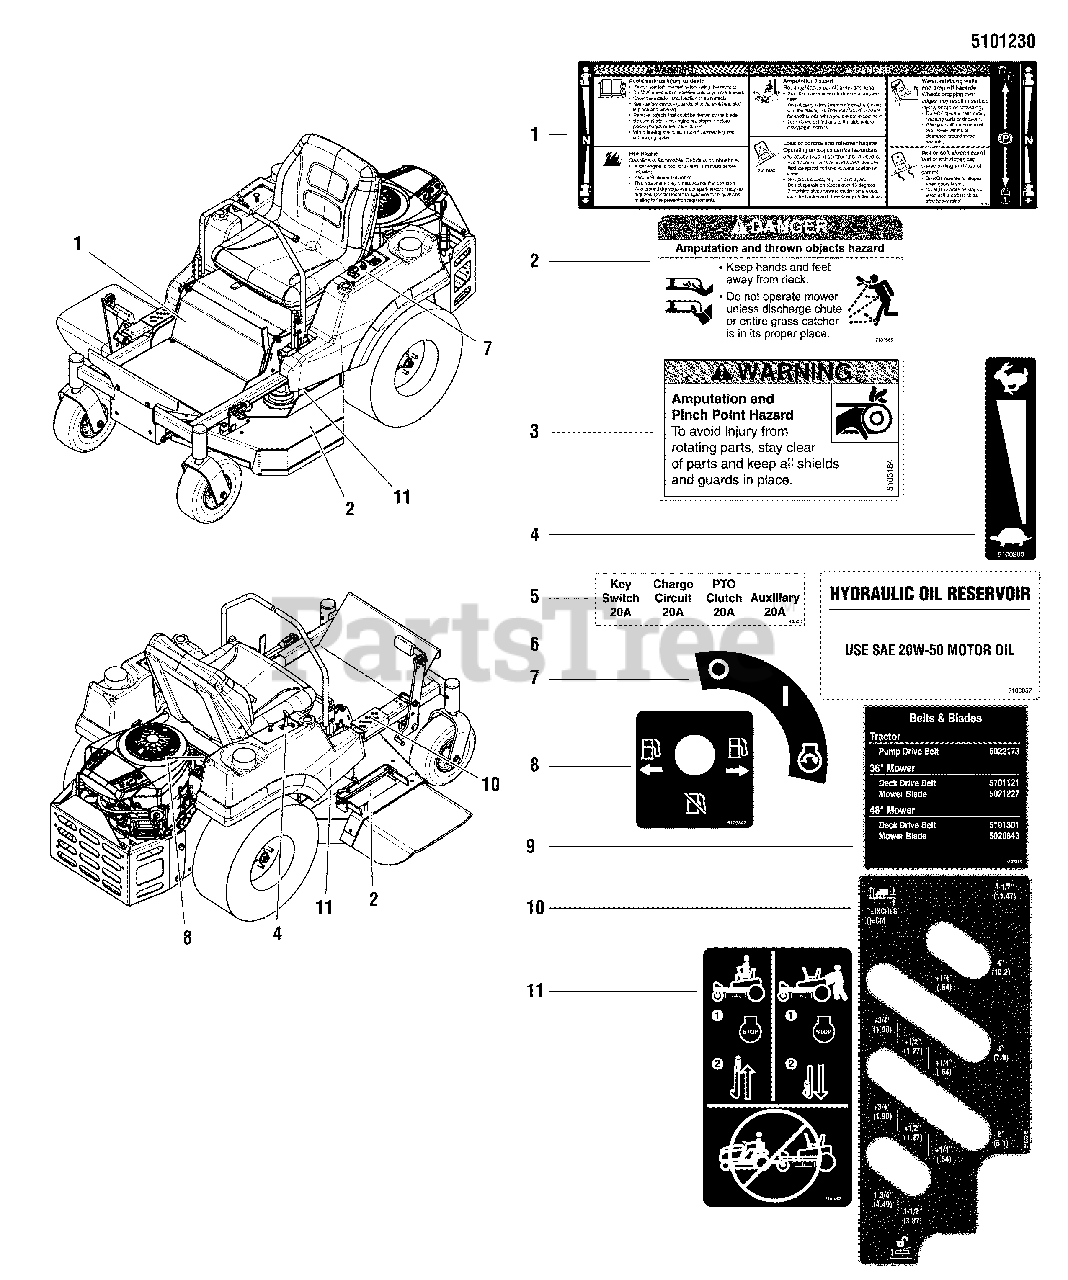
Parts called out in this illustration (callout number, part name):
1	DECAL, MAIN SAFETY
2	DECAL, DANGER DO NOT OPERATE W/O DEFLECT
3	DECAL, WARNING, HAND IN BELT, ENG ONLY
4	DECAL, Throttle Control
5	DECAL, FUSE LOCATION, 20-20-20-20
6	DECAL, HYDRAULIC OIL, SAE 20W50
7	DECAL, IGNITION CONTROL
8	DECAL, FUEL VALVE
9	DECAL, BELT & BLADE, S50X iCD
10	DECAL, CUT HEIGHT, S50X
11	DECAL, TRANSAXLE RELEASE
